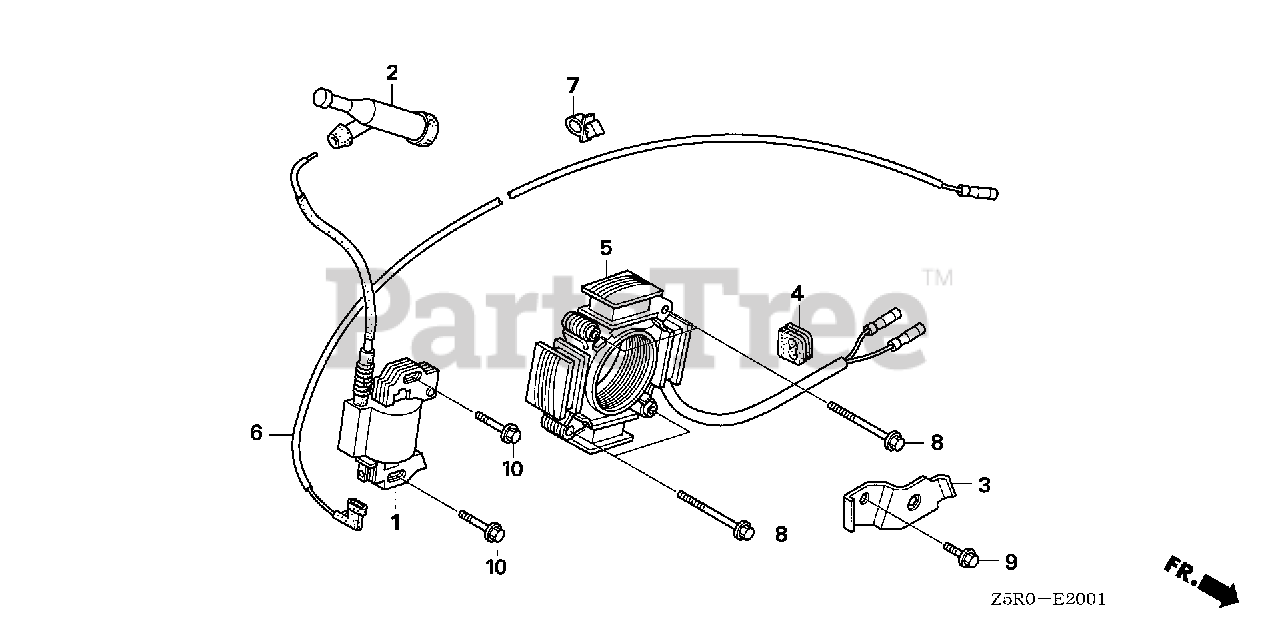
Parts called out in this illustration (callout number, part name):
1	COIL ASSY., IGNITION
2	CAP ASSY., NOISE SUPPRESSOR (NICHIWA Y-EZ RTFM256)
3	CLAMP, WIRE
4	GROMMET, WIRE
5	COIL ASSY., CHARGE (12V/18A)
6	WIRE, STOP SWITCH (430MM)
7	HOLDER, STOP SWITCH WIRE
8	BOLT, FLANGE (6X40) (CT200)
9	BOLT, FLANGE (6X12) (CT200)
10	BOLT, FLANGE (6X28) (CT200)
